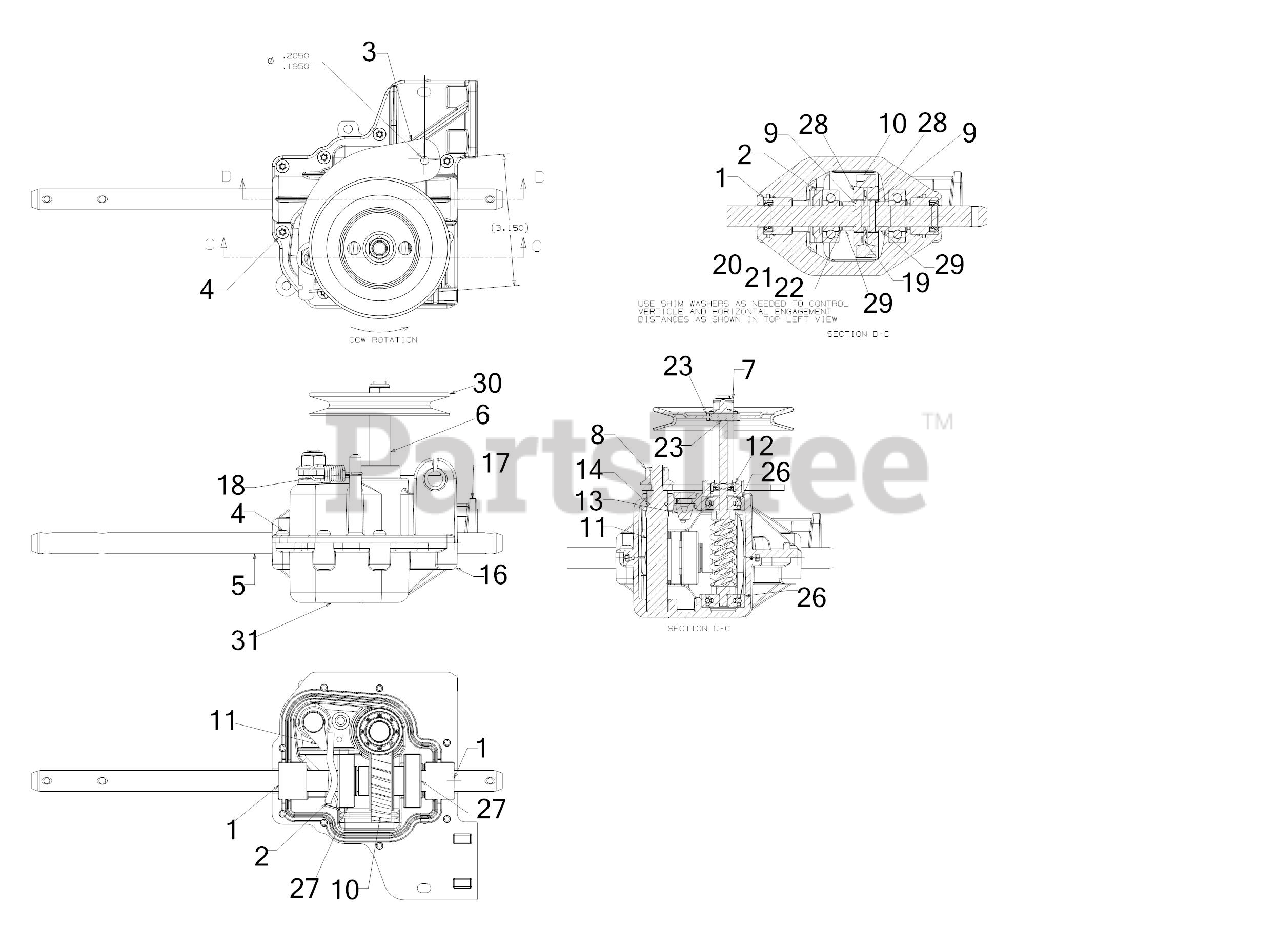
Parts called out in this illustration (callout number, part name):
1	BEARING ASSEMBLY
1	OIL SEAL
2	ACTUATOR PLATE
3	CLUTCH LEVER
4	SCREW .159 x .610
5	OUTPUT SHAFT
6	INPUT SHAFT
7	FLANGE LOCK NUT 5/16-18
9	DOWEL PIN
10	GEAR
11	ACTUATOR
12	OIL SEAL
13	RUBBER PLUG
14	ORING
16	LOWER HOUSING
17	UPPER HOUSING
18	EXTENSION SPRING
19	WASHER
20	FLAT WASHER .504 X.700X.010
21	WASHER
22	FLAT WASHER
23	THRUST WASHER
26	BALL BEARING
27	BEARING
28	BEARING
29	SPACER
30	PULLEY-3.36 OD
31	LABEL
